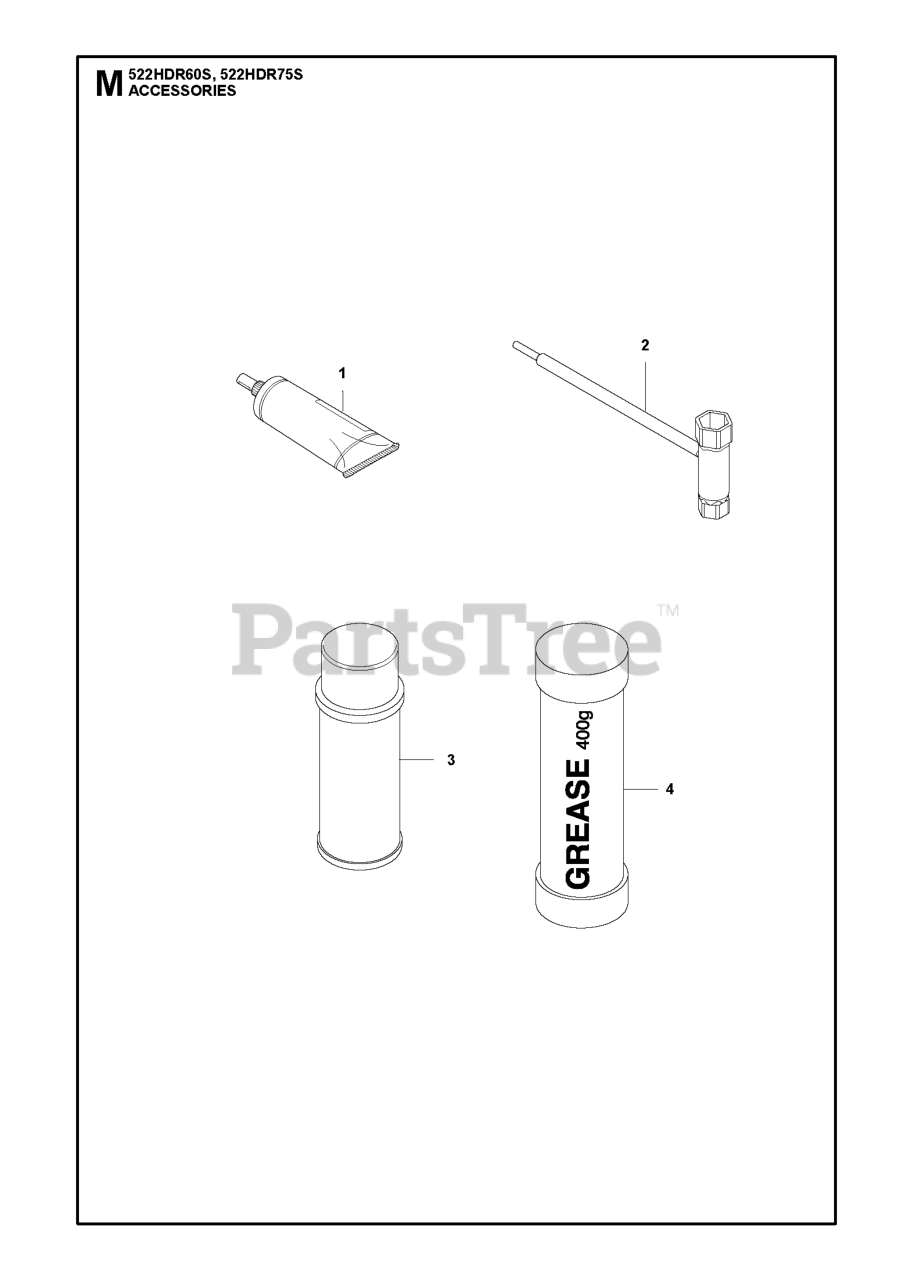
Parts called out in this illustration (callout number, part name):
1	GREASE ACCESSORY TUBE SHELL GA
2	COMBINATION WRENCH
4	HUS MULTI ADVANCE GREASE 400GR
